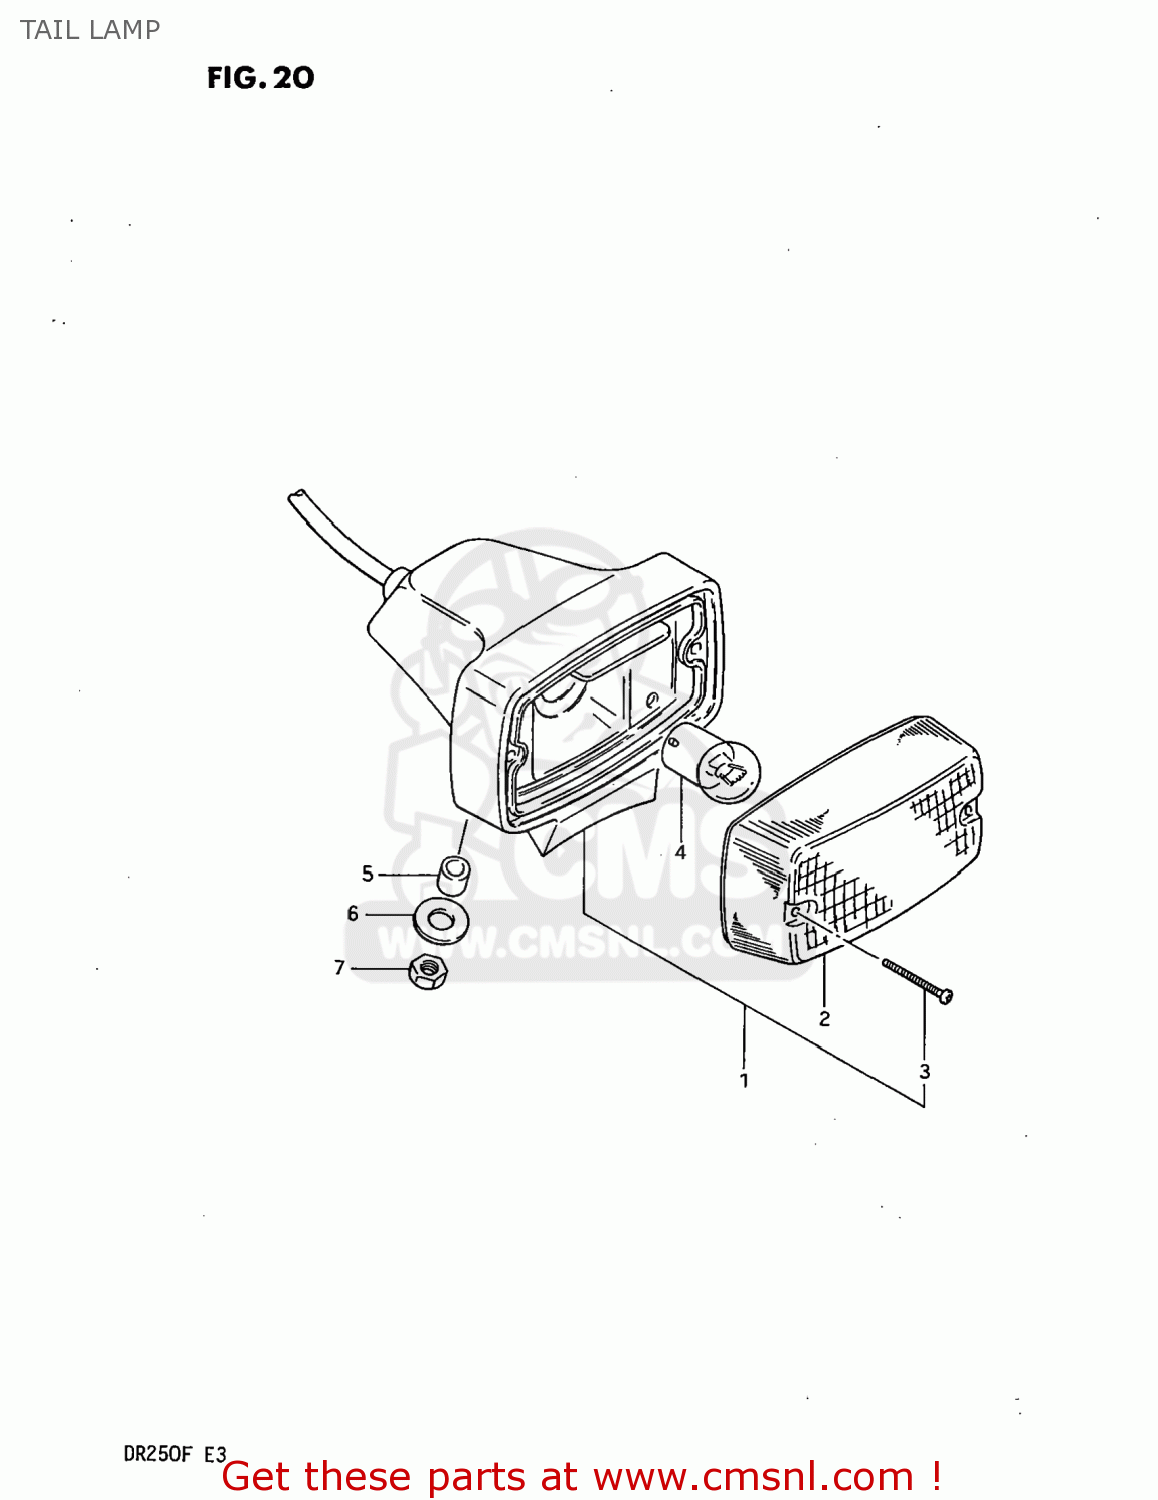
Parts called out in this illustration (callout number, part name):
1	LAMP ASSEMBLY,TAIL
2	LENS
3	SCREW,REAR COMBINATION LAMP LENS
4	BULB(6V5W,TOKAI DENSO)
5	SPACER (6.3X9.1X6.7)
6	WASHER
7	NUT
